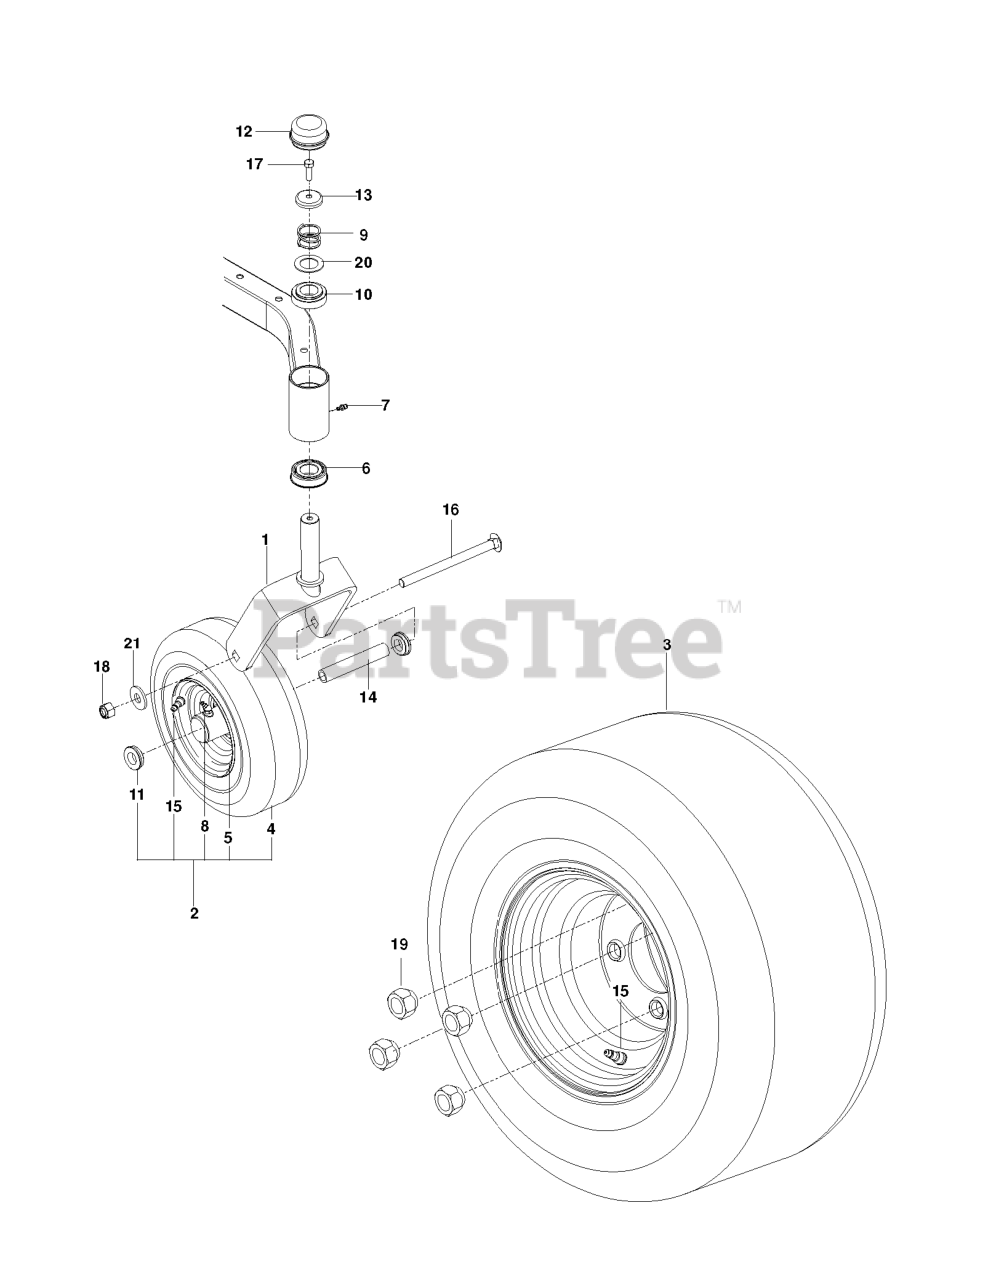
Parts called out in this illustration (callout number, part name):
1	YOKE.CASTER.ORANGE
2	WHEEL ASSY, WIDE, RZ
3	WHEEL.A500.18 X 9.5-8.SILVER
4	TIRE 11X6-5, 4 PLY
5	WHEEL 3.0 X 5.0
6	BEARING FLANGED
7	ZERK, 3/16, DRIVE IN
8	ZERK
9	SPRING, CASTER
10	BUSHING, CASTER
11	BUSHING, WHEEL, 3/4"
12	GREASE CAP
13	CASTER.PLUG
14	SPACER, PIVOT
15	VALVE STEM TR-412
16	RHSNB 1/2-13 X 7.5
17	5/16-18X1 HHB G5W/NY
18	NUT 1/2-13 HEX CNTRLK GR 5 ZD
19	LUG NUT 1/2F
20	WASHER, 1.025 ID X 1.64
21	WASHER.9/16 X 1 3/8 X 12 GA.
